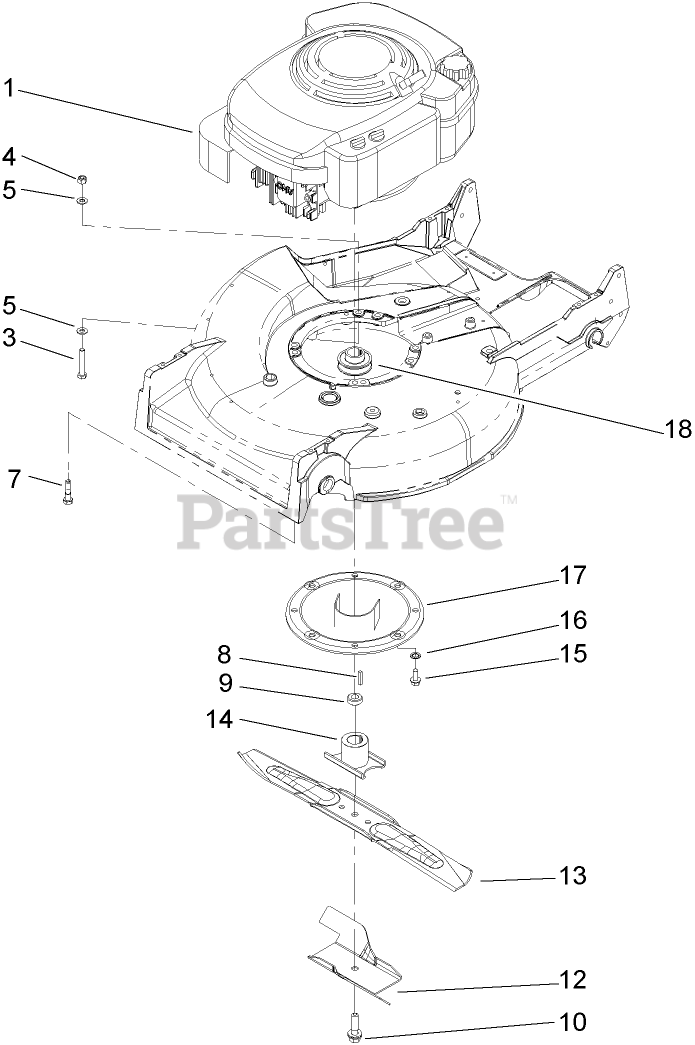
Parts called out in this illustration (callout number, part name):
1	Loose Parts Package
3	SCREW-HH
4	NUT-LOCK, NI
5	WASHER-PLAIN
7	SCREW-SHOULDER
8	KEY-SQUARE
9	SPACER-RETAINER, BLADE
12	STIFFENER-BLADE
13	BLADE-21 INCH
15	SCREW-HWHTF
16	WASHER-LOCK, INTERNAL
18	PULLEY-DRIVER
